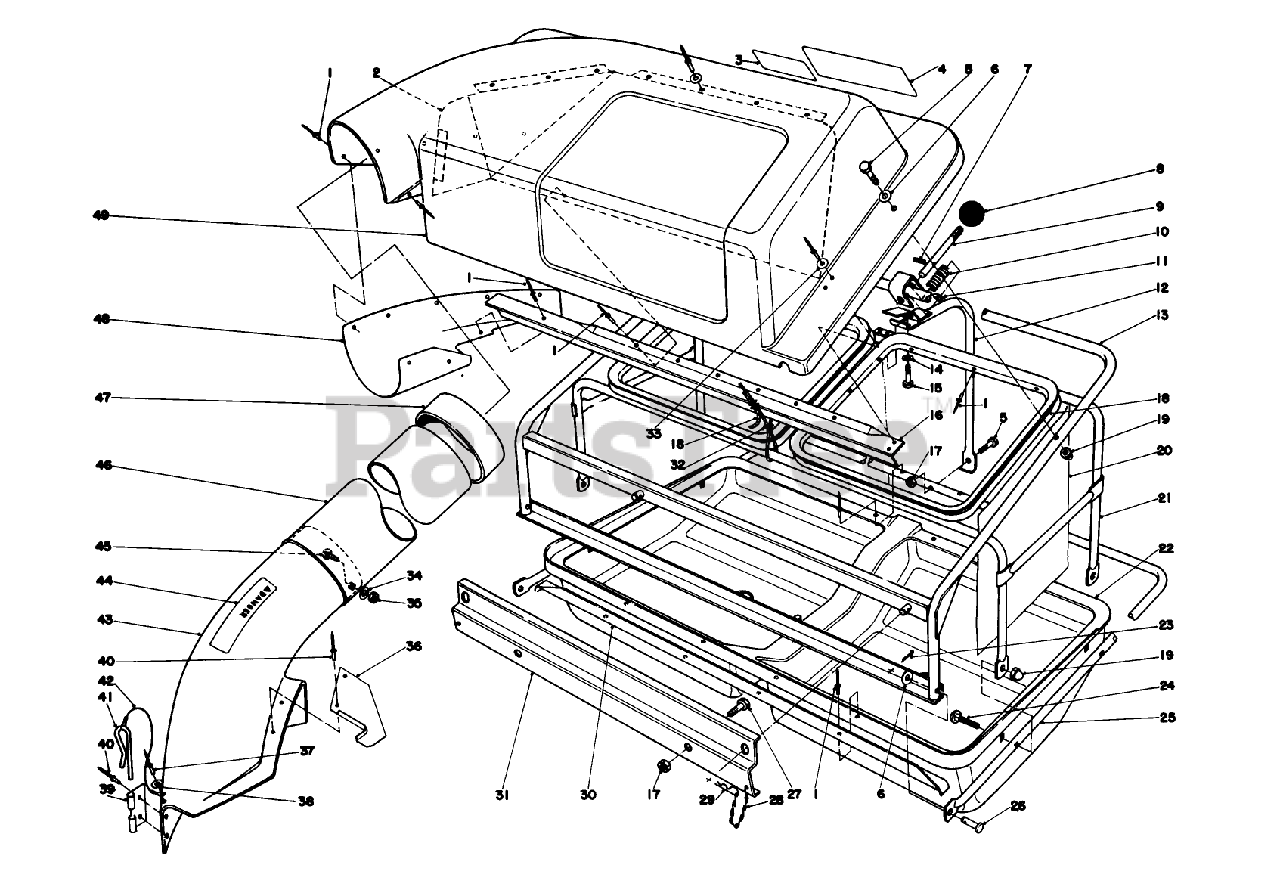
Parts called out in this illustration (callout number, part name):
5	SCREW-HH
6	WASHER-PLAIN
7	PIN-ROLL, SLOT
11	WASHER-FLAT
14	WASHER-LOCK
15	SCREW-HH
17	NUT-LOCK, CONE
19	NUT-ACORN
23	PIN-COTTER
24	SCREW-CARR
26	PIN-CLEVIS
27	SCREW-HH
29	PIN-HAIR
33	WASHER-FLAT
34	WASHER-FLAT
35	NUT-KEPS
36	CHUTE SUPT BRKT
37	RIVET-BLIND
38	WASHER-PLAIN
39	BRACKET-MOUNTING, CHUTE
40	RIVET-BLIND
41	PIN-LOCKING, CHUTE
42	LANYARD
43	CHUTE ASM
45	BOLT-CARR
47	DUCT SEAL
